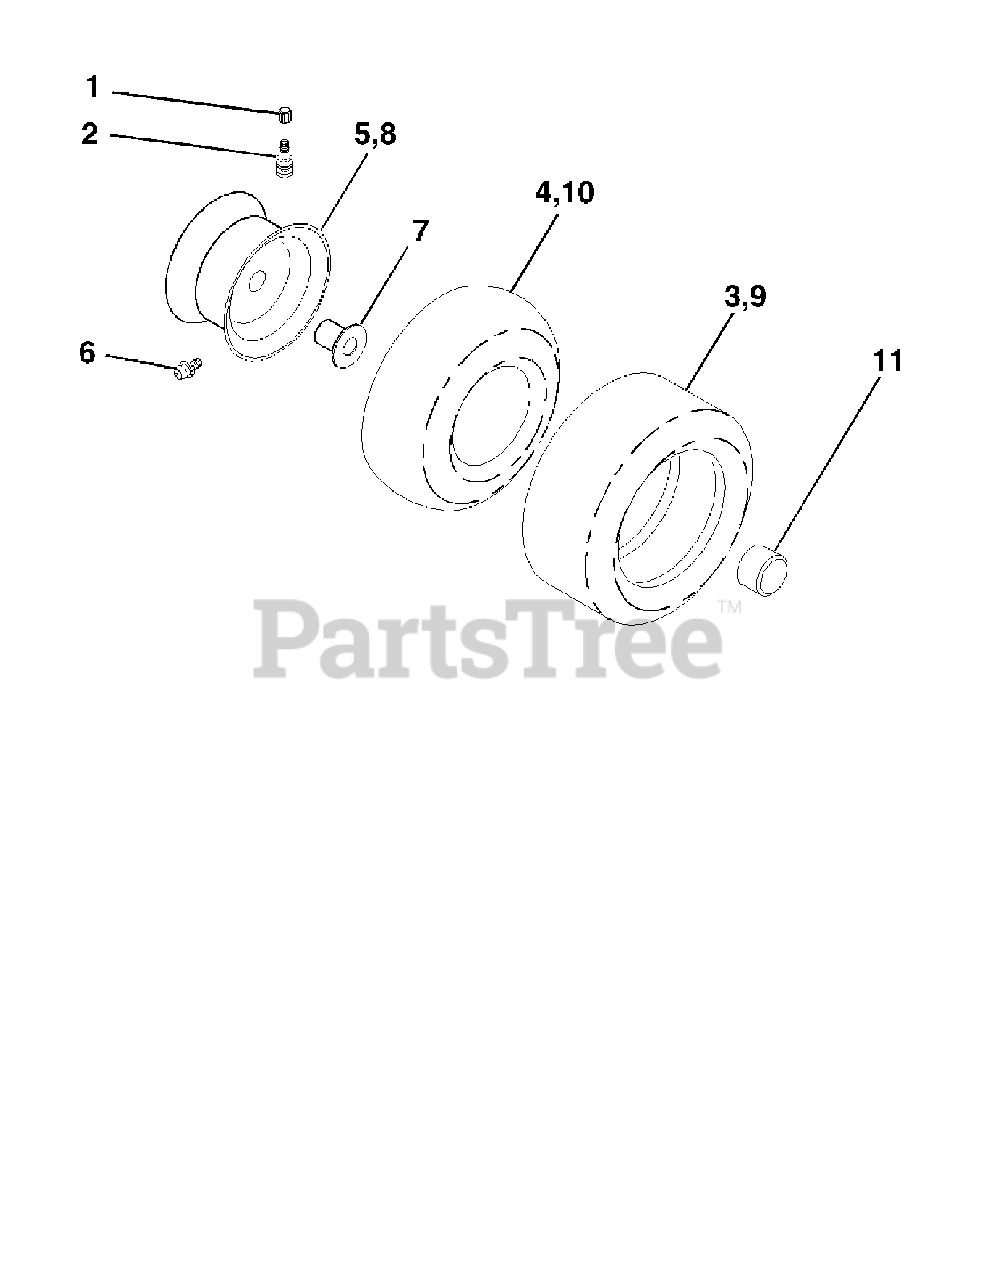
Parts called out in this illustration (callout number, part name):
1	VALVE CAP
2	VALVE STEM LT
3	TIRE.FRONT.TURF.MASTER.15X6-6
4	TUBE.5.3/4.5/6
5	RIM.FRONT.6".YELLOW
6	FITTING LT
7	Flange Bearing
8	RIM REAR 8"
9	TIRE.TURF.MASTER.20X10-8
11	CAP.AXLE.FRONT.YELLOW
